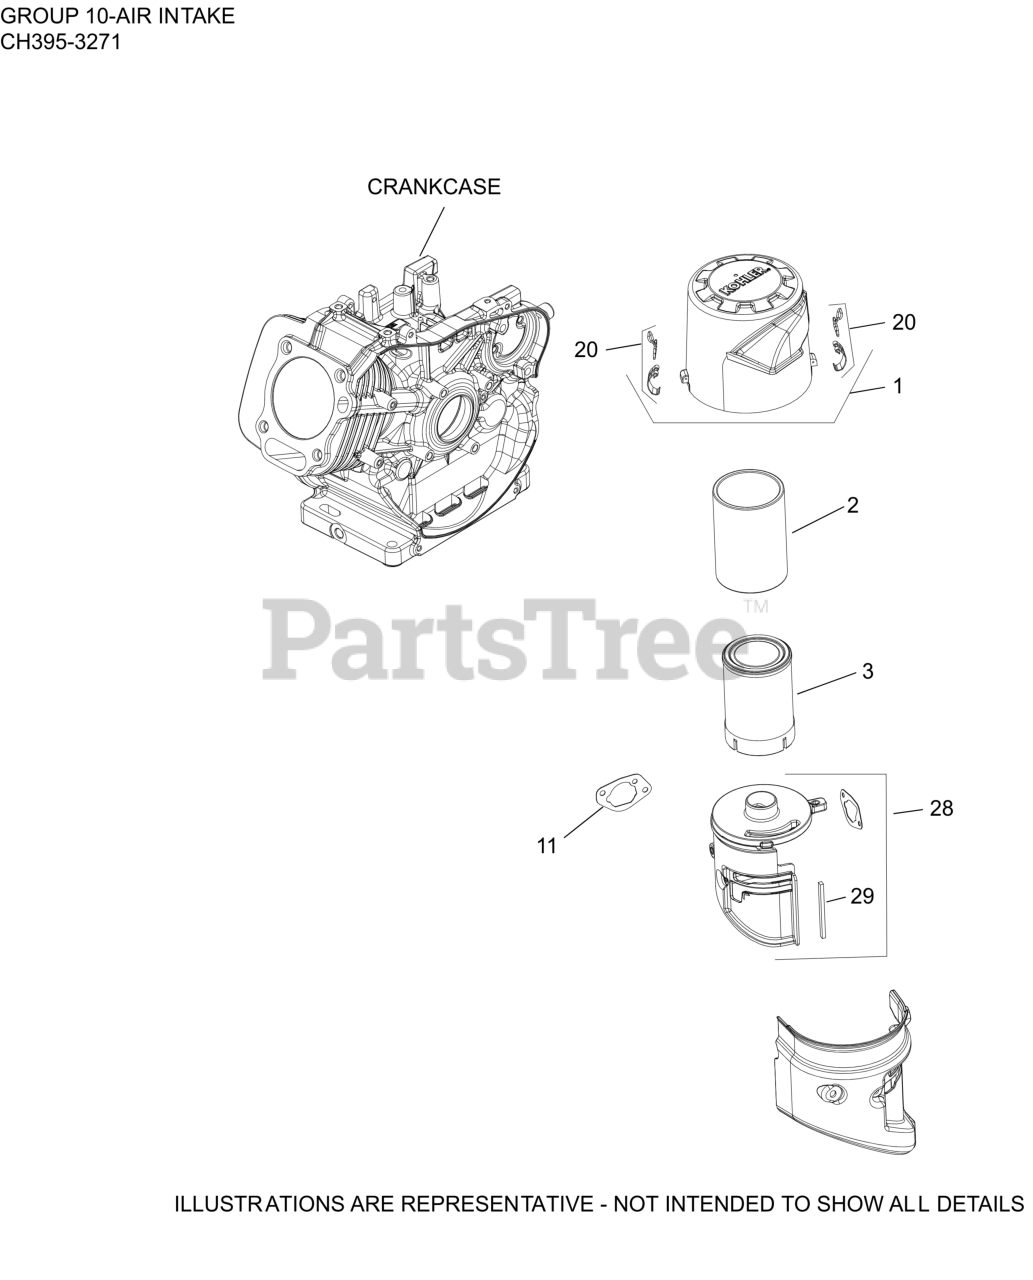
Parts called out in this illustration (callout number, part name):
1	COVER, AIR CLEANR ASSEMBLY
2	ELEMENT, PRE-CLEANER
3	ELEMENT, AIR FILTER
11	GASKET, AIR CLEANER
20	KIT, LATCH CLIP
28	KIT, AIR CLEANER BASE ASSEMBLY
